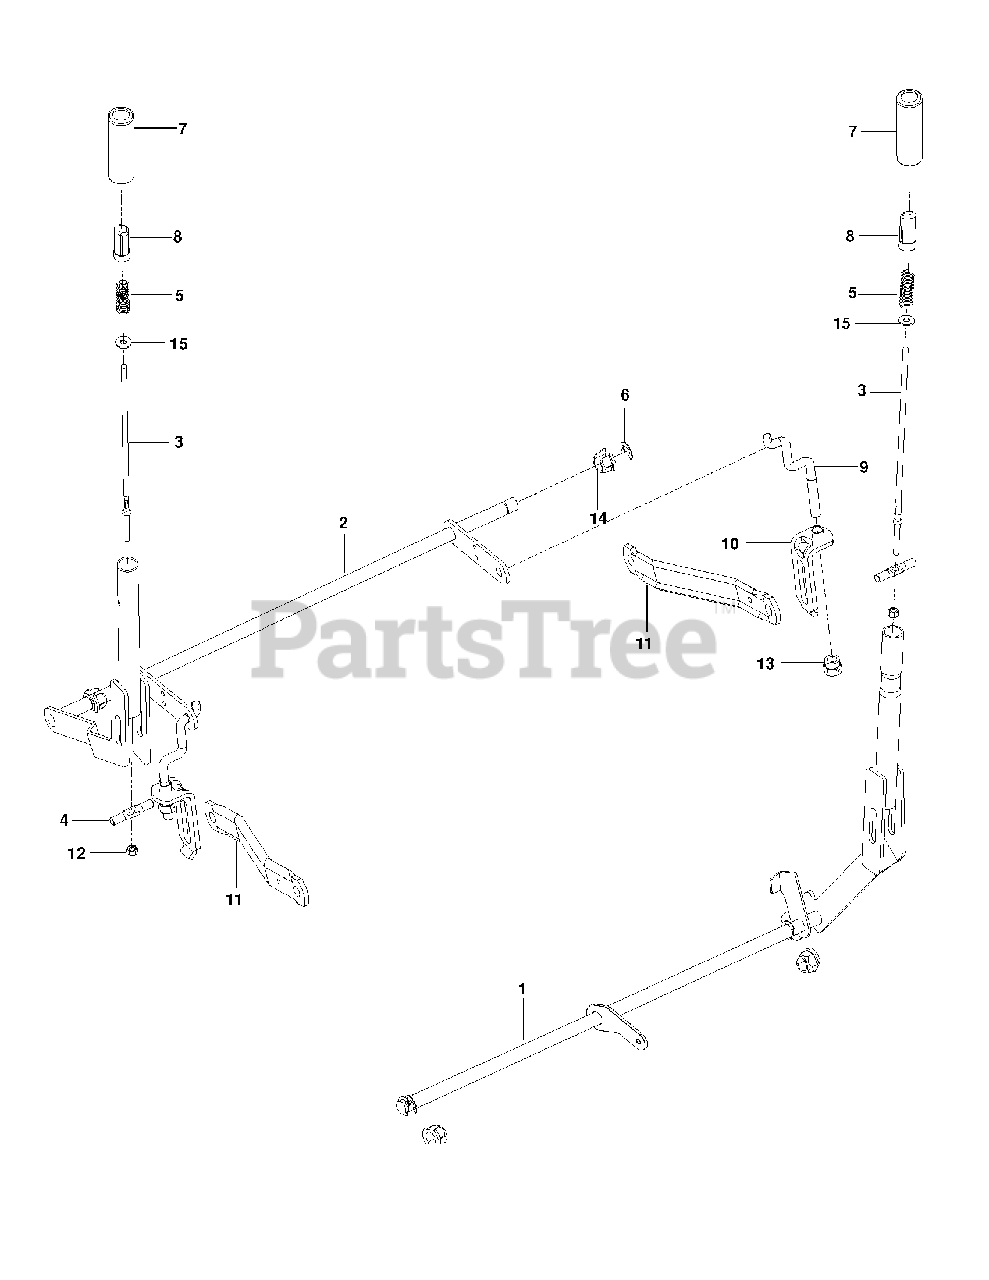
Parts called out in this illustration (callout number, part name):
1	SUB.ASM.SHAFT.BRAKE.WLDMNT.MED
2	SHAFT.LIFT.MED.BLACK
3	ROD, HANDLE RELEASE
4	RB ROD, LATCH RELEASE
5	SPRING, COMPRESSION
6	E-RING 5/8
7	GRIP, HANDLE, BLACK 4"
8	BUTTON, PUSH, BLACK
9	LINK, REAR SUSPENSION
10	ASSEMBLY, BRKT LINK
11	ARM.SUSPENSION.MOWER
12	LOCKNUT.NYLOC.1/4-20
13	NUT, LIFT LINK 7/16-20
14	PLASTIC NUT
